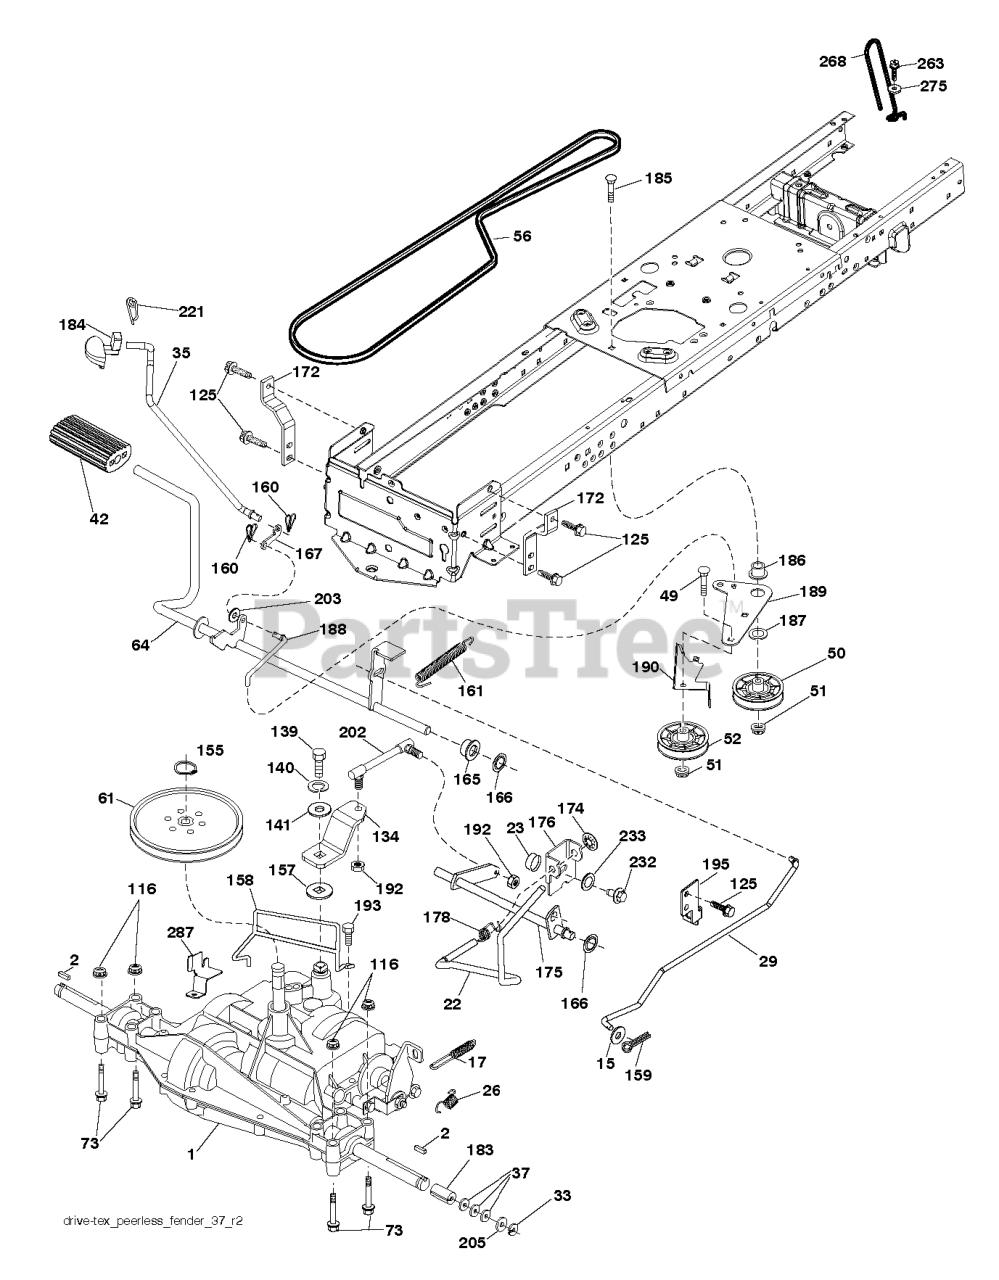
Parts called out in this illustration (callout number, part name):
2	KEY, 1/4 SQ X 1 1/4
7	HUB.PNT.GT.PM.1IN.AXLE.E-DIP
15	WASHER PLAIN WASHER 3/8 X 0.08
17	SPRING.BRAKE.HG3000/3500
26	SPRING.RETURN.CRUISE
33	E RING HYT
35	ROD ROD.PARKINGBRAKE.GT.HUSQ/P
42	PEDAL COVER
50	IDLER.FLAT.910.OFFSET
51	NUT LOCK FLG 3/8-16 UNC
52	IDLER.V-GROOVE.910.OFFSET
64	SHAFT.ASM.PEDAL.BRK.CNTR
70	CONSOLE.ASM.RH.GT.FC.HUSQ
73	BOLT HEX FLGHD 5/16-18X3 GR. 5
80	STRAP.TORQUE.YT.G700
99	ROD ASSY BYPASS G730
121	BRACKET STRAP TORQUE
125	SCREW
145	WASHER.AXLE.FLANGE.HG-3000
153	RETAINER M
161	SPRING, RETURN LT
163	ROD PEDAL CONTROL
166	NUT.PUSH.625
167	LATCH.BRAKE.SPRING
170	KEEPER.V-IDLER.CENTER.
177	PIN COTTER;LOCKING;BOWTIE;1IN
184	HANDLE.PARKING.BRAKE.H (BLK)
186	SPACER.RETAINER
188	LINK.CLUTCH.GROUND DRIVE.LONG
189	BELLCRANK.GROUND.DRIVE.TEX.
190	KEEPER.BELLCRANK.DRIVE
196	SCREW 3/8-16X1
203	WASHER 11/32 X 11/16 X 14 GA T
206	BRACKET.MOUNT.CRUISE.LATCH
209	ROD ROD.CRUISECONTROL.GT.HUSQ/
210	ROCKER.ASM.PEDAL.CONTR
211	BEARING.NYLON
213	KNOB.CONTROL.CRUSIE.HU
214	PEDAL.FORWARD.PAD.TEX
215	PEDAL.COVER.REVERSE.CRD.X428BK
220	REFLECTOR.RH.TEX GT
221	RETAINER.SPRING.CLIP.H
222	WASHER 21/32 X 1-1/4 X 10 GA.
286	BOLT.5/16-18X2.5
